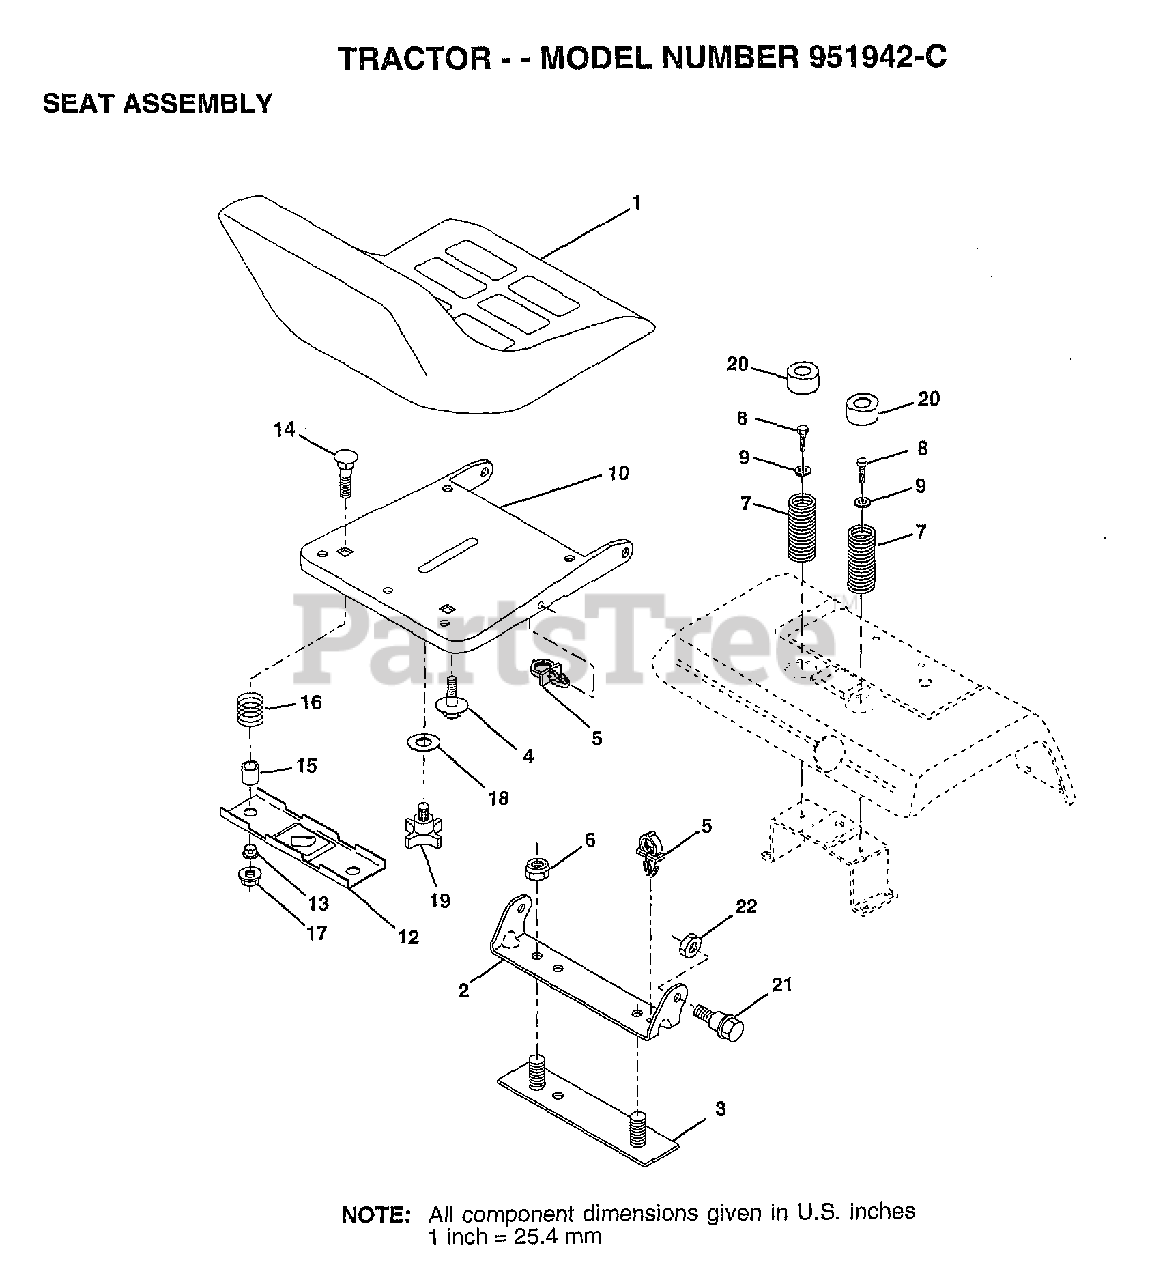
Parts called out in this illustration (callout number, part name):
2	BRACKET PVT SEAT
3	STRAP ASM FENDER
4	"BOLT,SHOULDER"
5	CLIP.PUSH-IN.HING
7	SPRING COMPRESSIO
8	SCREW LT
9	WASHER
12	BRKT SWITCH
13	BUSHING
15	SPACER SPLIT
16	SPRING COMPRESSED
18	WASHER
19	"KNOB 1/2"" YT"
20	CAP SPRING
21	BOLT.SHLD.5/16-18
